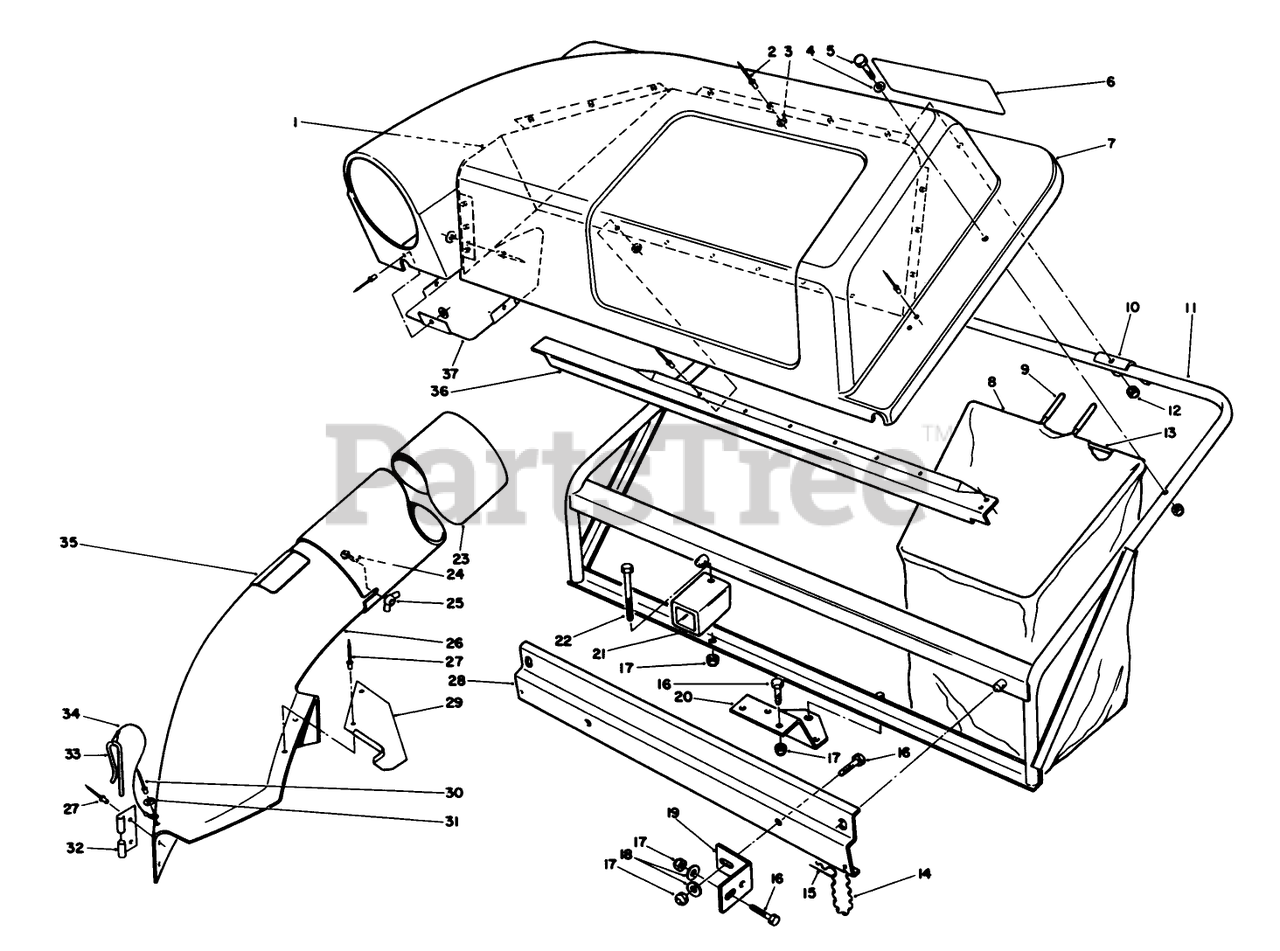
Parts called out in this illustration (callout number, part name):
2	RIVET-POP
3	WASHER-FLAT
4	WASHER-PLAIN
5	SCREW-HH
8	BAG ASM
9	GRIP-HANDLE, BAG
12	NUT-ACORN
15	PIN-HAIR
16	SCREW-HH
17	NUT-LOCK, NI
18	WASHER-PLAIN
20	MTG PLATE *B
22	SCREW-HH
24	BOLT-CARR
25	NUT-WING SPECL
26	CHUTE ASM
27	RIVET-BLIND
29	CHUTE SUPT BRKT
30	RIVET-BLIND
31	WASHER-PLAIN
32	BRACKET-MOUNTING, CHUTE
33	PIN-LOCKING, CHUTE
34	LANYARD
